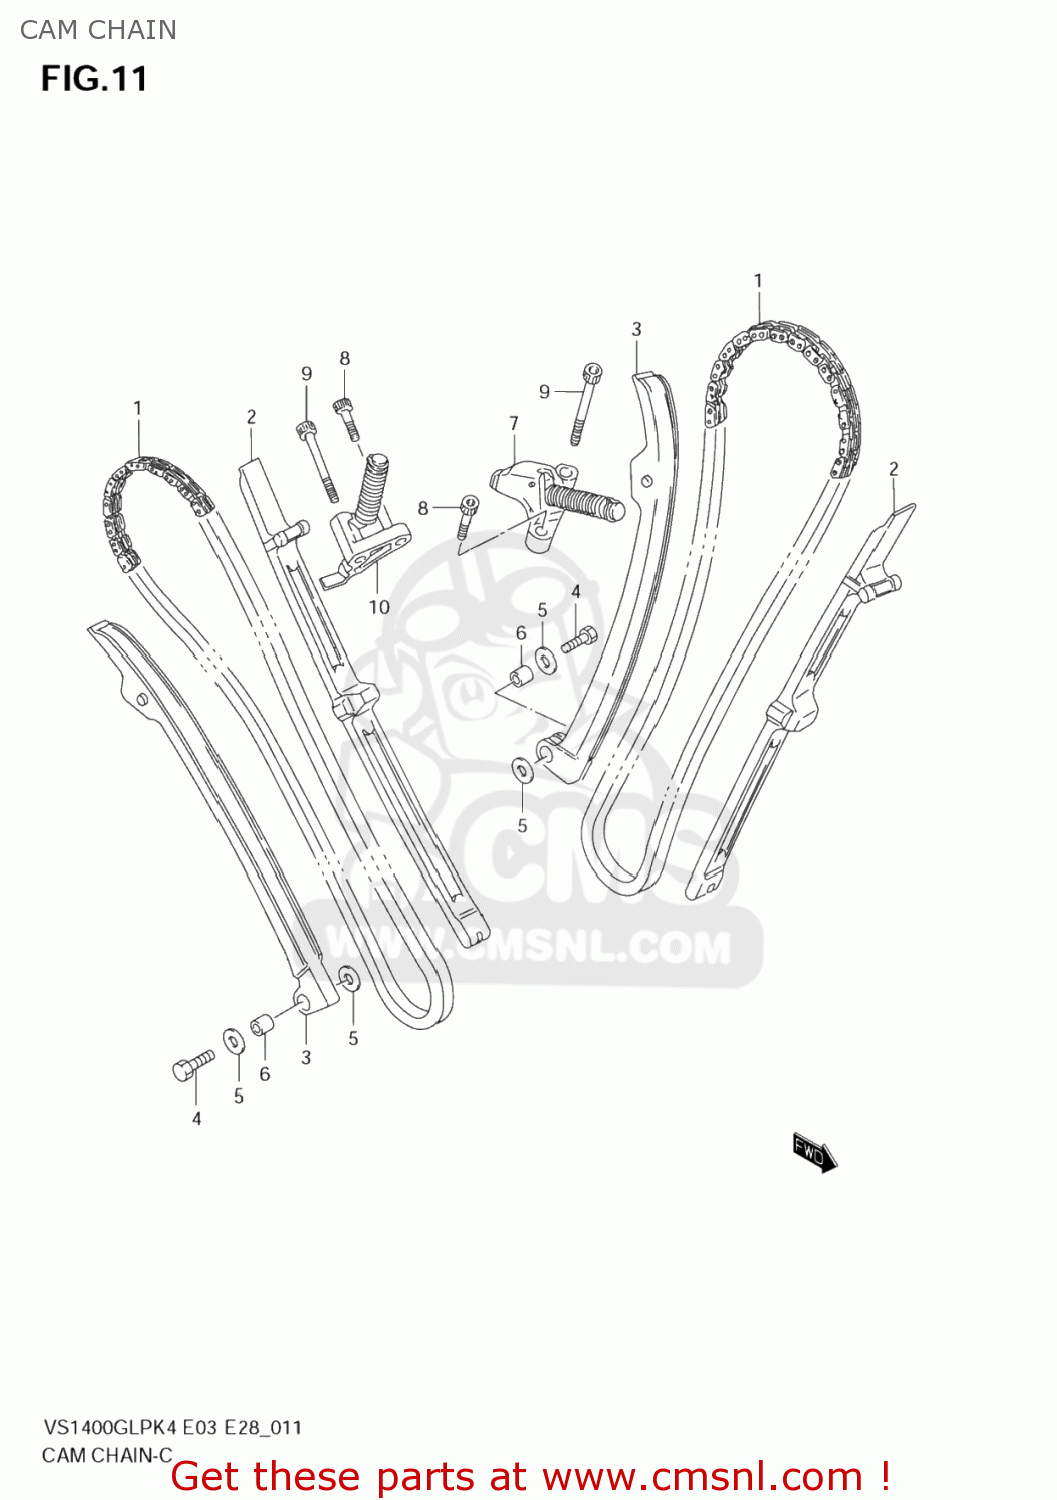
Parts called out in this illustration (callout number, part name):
1	CHAIN,CAMSHAFT DRIVE
2	GUIDE,CAM CHAIN
3	TENSIONER,CAM CHAIN
4	BOLT(6X26)
5	WASHER
6	SPACER(6X11X9)
7	ADJUSTER ASSY,FR TENSIONER
8	BOLT
9	BOLT
10	ADJUSTER ASSY,RR TENSIONER
